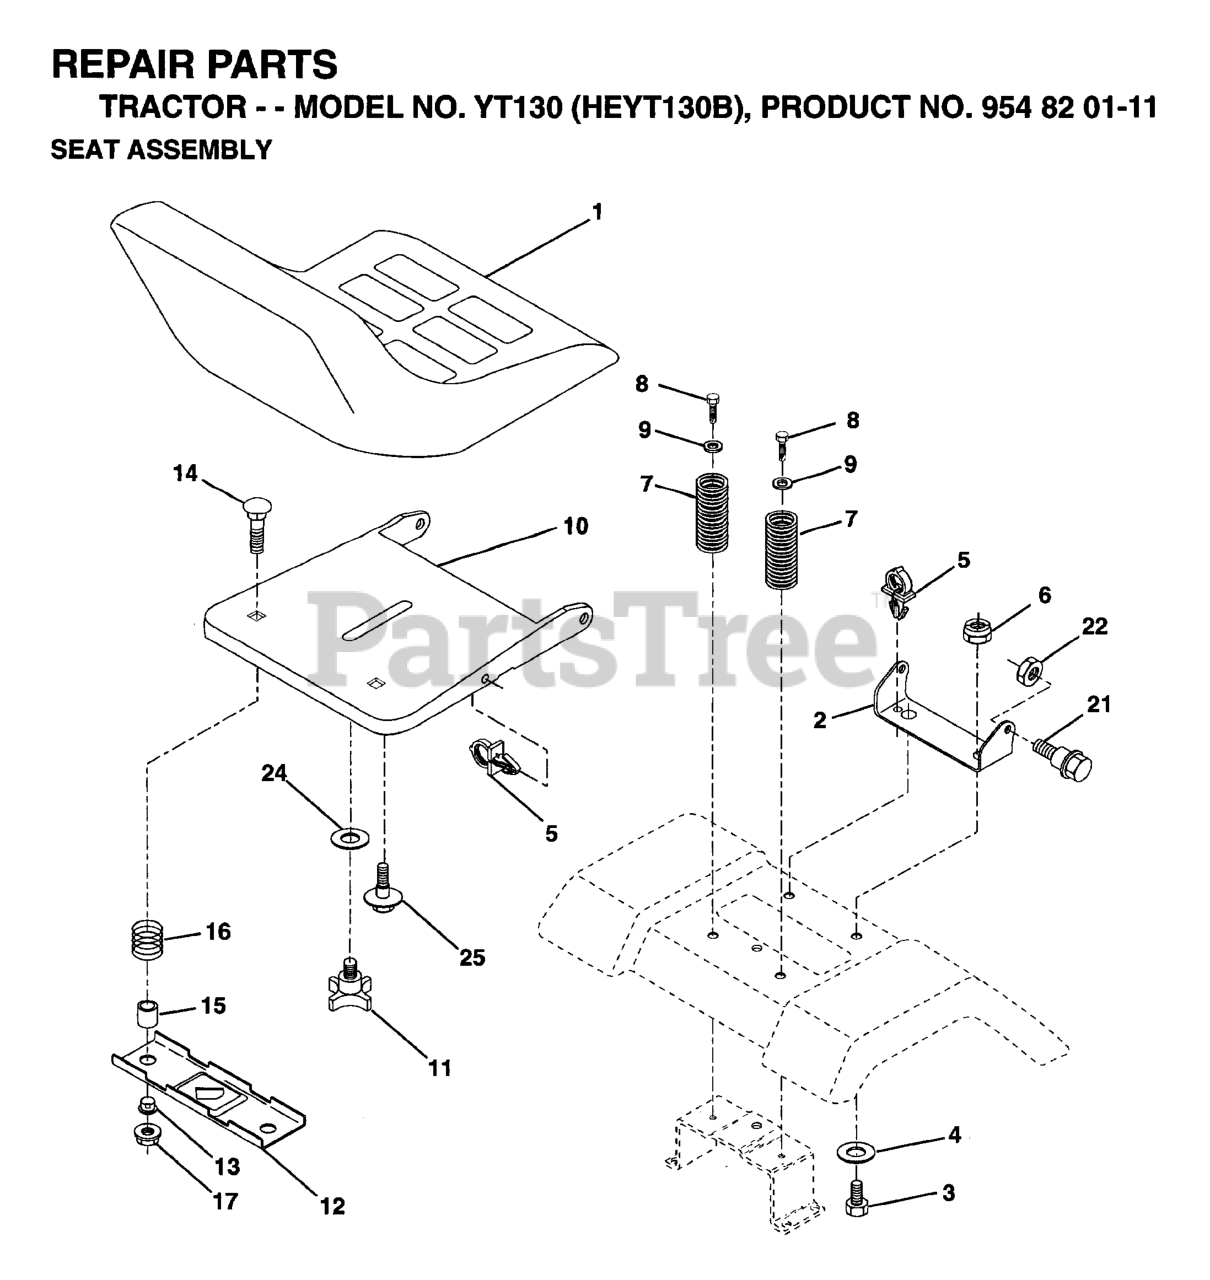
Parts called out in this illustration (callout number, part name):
1	SEAT
2	SEAT PIVOT BRKT
3	BOLT
6	NUT
7	SPRING COMPRESSION
8	SCREW GTV
9	WASHER
10	SEAT PAN
11	KNOB 1/2" YT
12	BRKT SWITCH
14	Bolt Rdhd. Sht. Nk 1/4-20 x 1-3/8
15	SPACER SPLIT 28X.96
17	NUT T
21	BOLT.SHOULDER.5/16-18
22	LOCKNUT
25	BOLT,SHOULD
